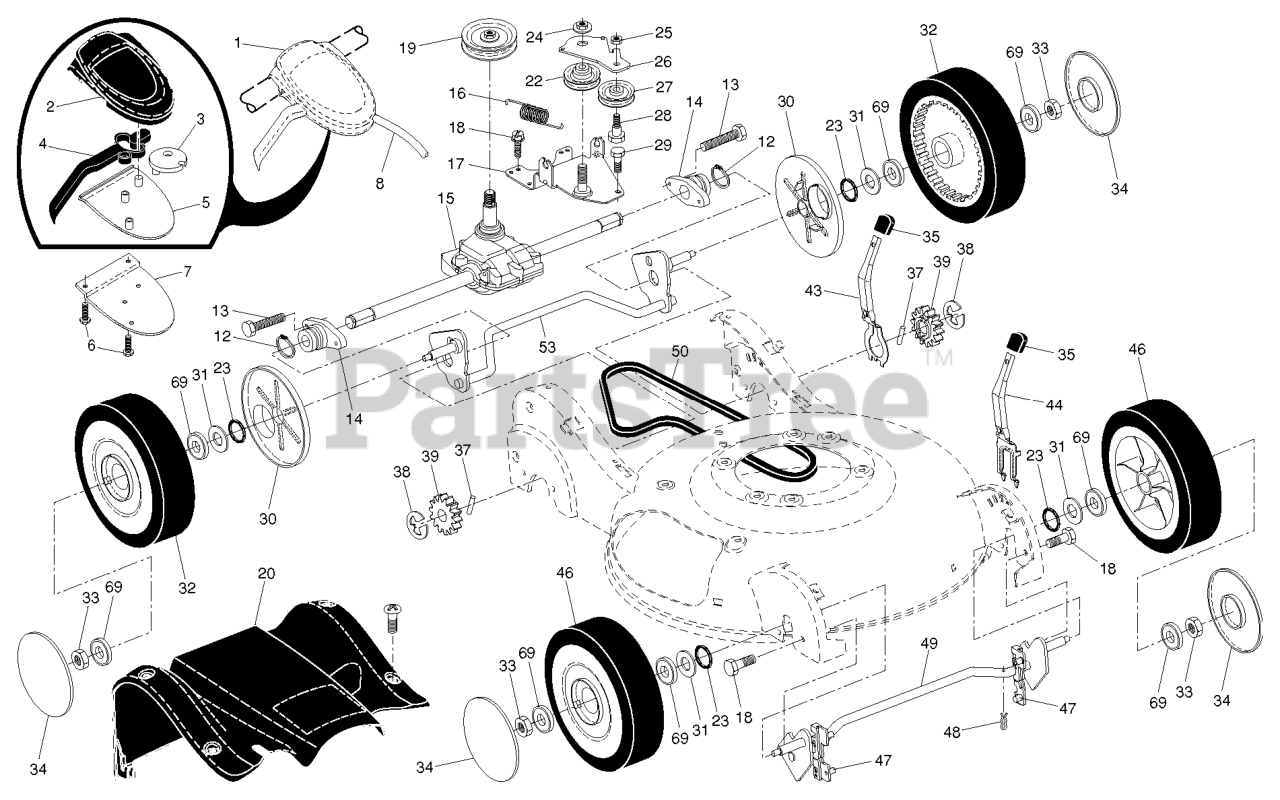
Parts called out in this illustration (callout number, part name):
1	Drive Control Assembly, Complete
2	COVER TOP AUTO WALK CONTROL
3	PULLEY.CAM.DRIVE.CONTROL.HV
4	LEVER.BLACK
5	COVER BOTTOM AUTO WLK CONTROL
6	SCREW, PHILLIPS HEAD 10 X 5/8
7	BRACKET.DRIVE.CONTROL.MOUNT.BL
8	ASM.CABLE.
12	RETAINING RING (2 2)(3 2)
13	SCREW.1/4-20X21/4.HEX.
14	BEARING / AXLE SUPPORT
15	TRANSMISSION.21.HV.RWGD.AW/EZ
17	BRACKET, GEAR CASE / DRIVE
19	RP PULLEY.DRIVE.EZ
20	COVER.DR.ASM.408006X418.CE
22	PULLEY.IDLER.V-BELT
23	O-RING..070X.487.NEOPRENE
24	NUT.HEX.FLANGE.3/8-16.LOCKNUT
25	NUT.CENTERLOCK.5/16-
26	ARM.IDLER.BZP
27	IDLER PULLEY
28	SHOULDER BOLT
29	SCREW 14-20 X 5/8
30	DUST COVER, WHEEL
31	WASHER.FLAT.1/2
32	WHEEL.9X2.25.LP.TIGER.BLACK
33	NUT.HEX.FLANGE.3/8-16.LO(3 2)
34	HUBCAP.WHEEL.5.SPOKE.SILVER
35	KNOB.SELECTOR.SPRING.BLACK(3 2
37	PAWL, DRIVE
38	E-RING 7/16 RE
39	PINION.14.TEETH.FGD
43	LEVER, SELECTOR, HEIGHT, REAR
44	LEVER, SELECTOR, HEIGHT, FRONT
46	WHEEL.9X2.25.LP.TIGER.BLK
47	BUSHING.FRONT.TORQUE.SHAFT
48	SPRING RETAINER
49	SHAFT FRONT
50	BELT, DRIVE
53	SHAFT.ASM.REAR.TORQUE.HV.BZP
69	BEARING.8".WHEEL
